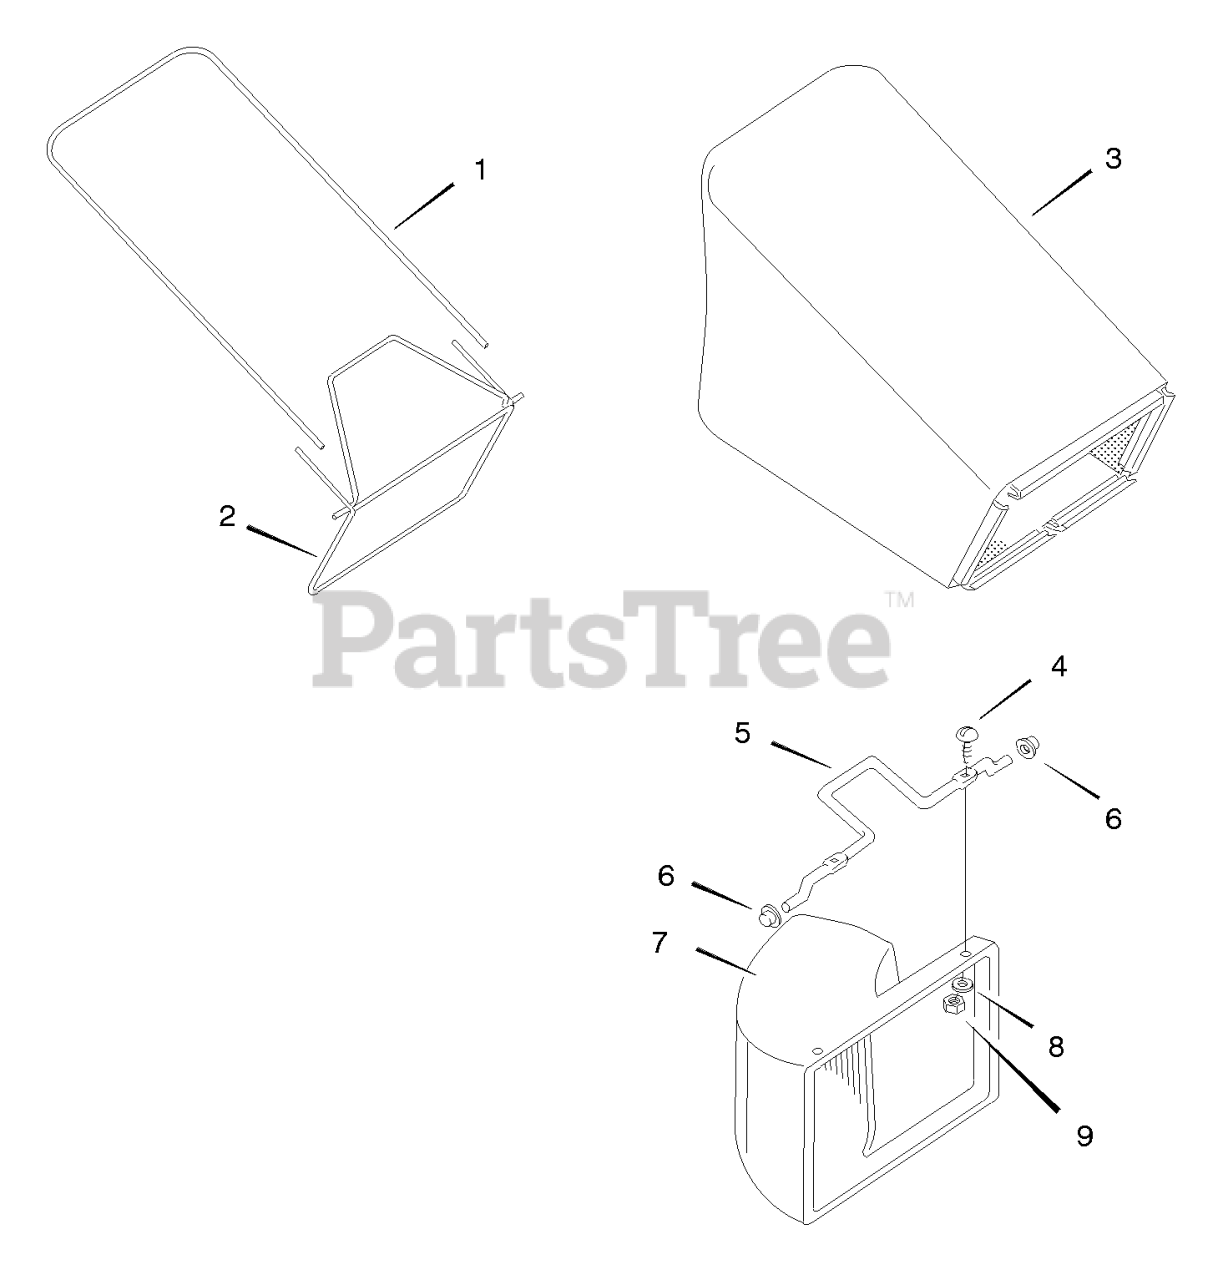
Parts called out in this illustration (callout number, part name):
1	Support, Bag
2	Frame Assembly
3	Bag, Cloth
5	Frame Assembly
6	Push On Cap
7	Side Discharge Attachment -
8	Washer
